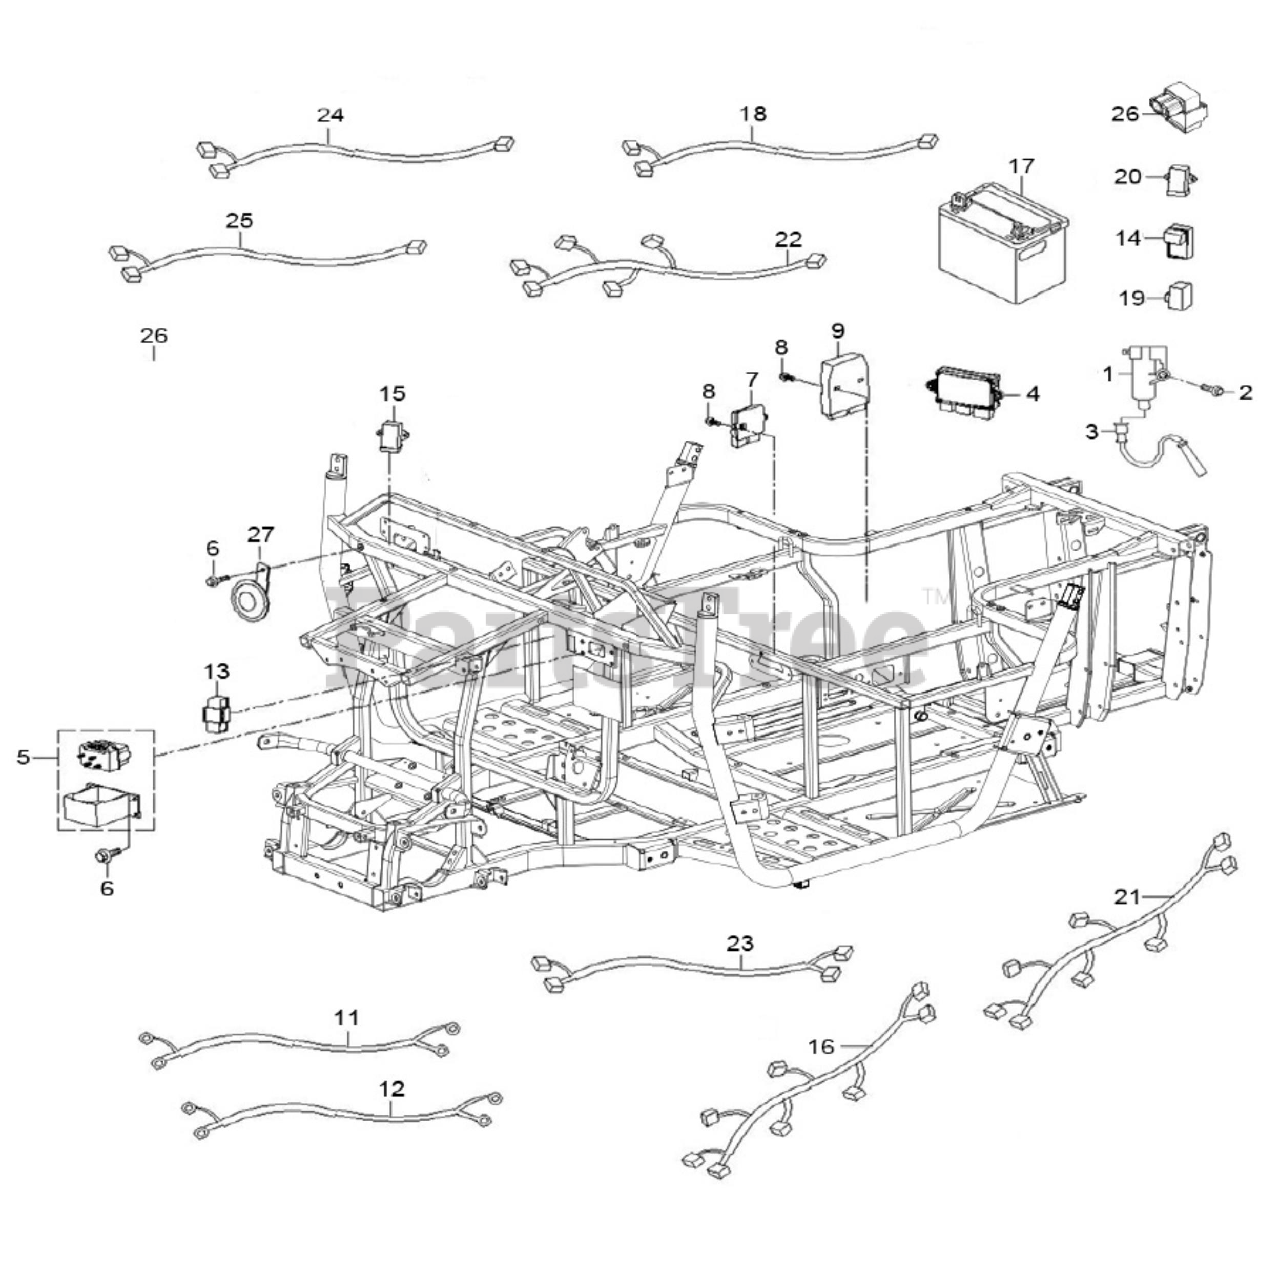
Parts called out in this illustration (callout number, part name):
1	Ignition Coil
2	Hexagon Flange Bolt M6x40
3	connector wire for ignition coil
3	IGITION CABLE
5	Winch Relay
6	Hexagon Flange Bolt M6x16
7	ECU CONTROLLER 550
7	ECU CONTROLLER 750
8	Hexagon Flange BoltM6x20
10	Starter Relay
11	CABLE - WINCH RELAY OUTLET
12	WINCH CABLE
13	RELAY - RADIATOR FAN
14	Main Relay Assy
15	RELAY - 2W/4W
16	MAIN CABLE ASSEMBLY
18	POWER POSITIVE CABLE
19	FLASH APPARATUS
20	OVERSPEED GOVERNOR
21	CABLE - EFI KIT
22	CABLE - GROUND
23	CABLE - RECTIFIER OUTLET
24	CABLE - SWITCH KIT 1
25	CABLE - SWITCH KIT 2
26	CABLE - EPS
27	HORN ASSEMBLY
28	CABLE - MAIN
29	POWER POSITIVE CABLE
